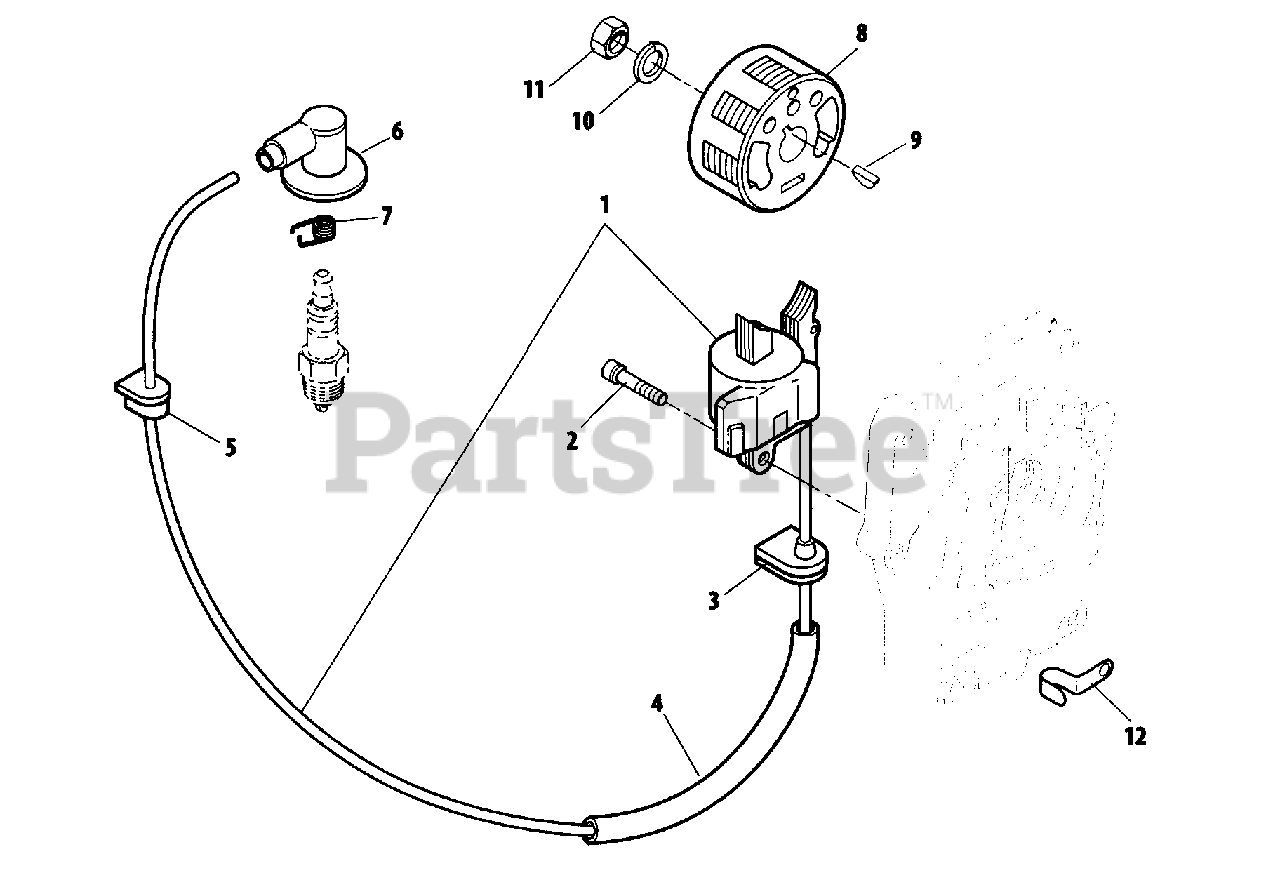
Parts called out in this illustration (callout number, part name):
1	COIL
2	SCREW - 5X20
3	GROMMET
4	TUBE
5	GROMMET
6	CAP, SPARK PLUG
7	TERMINAL, SPARK PLUG CAP
8	FLYWHEEL
9	KEY - 3X10
10	LOCKWASHER - 10
11	NUT - 10
12	CLIP, WIRE
